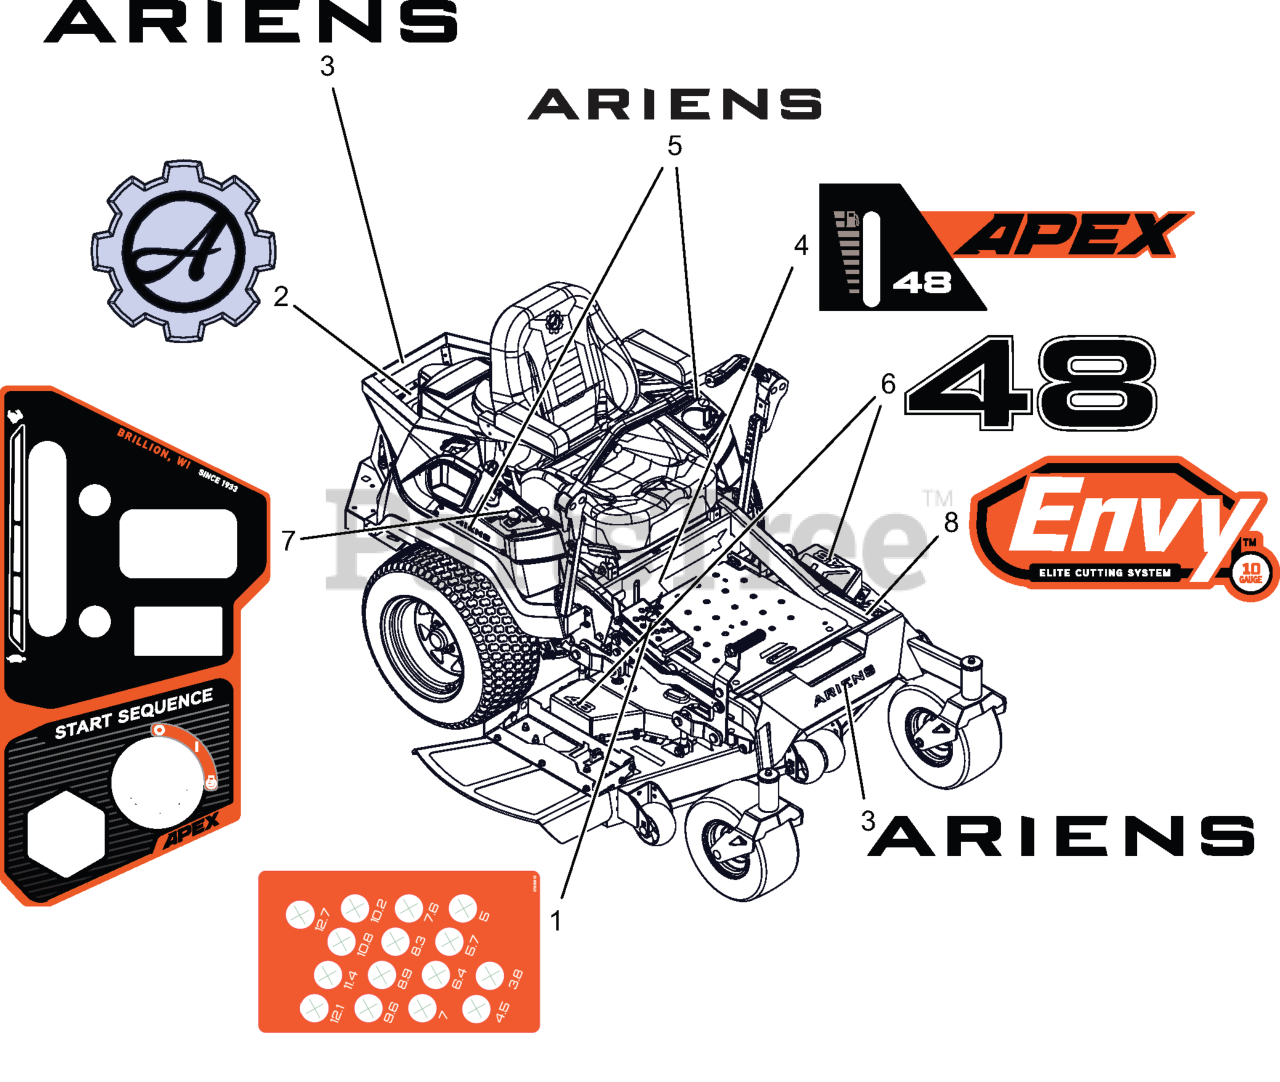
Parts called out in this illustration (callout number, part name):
1	DECAL, APEX HOC METRIC
2	DECAL- ARIENS GEAR BADGE
3	DECAL- ARIENS 9.625" BLACK
4	DECAL- APEX 48 KICKPLATE
5	DECAL- ARIENS 6.000" BLACK
6	DECAL- DECK 48
7	DECAL- DASH -APEX & ZENITH
8	DECAL- DECK -ENVY
